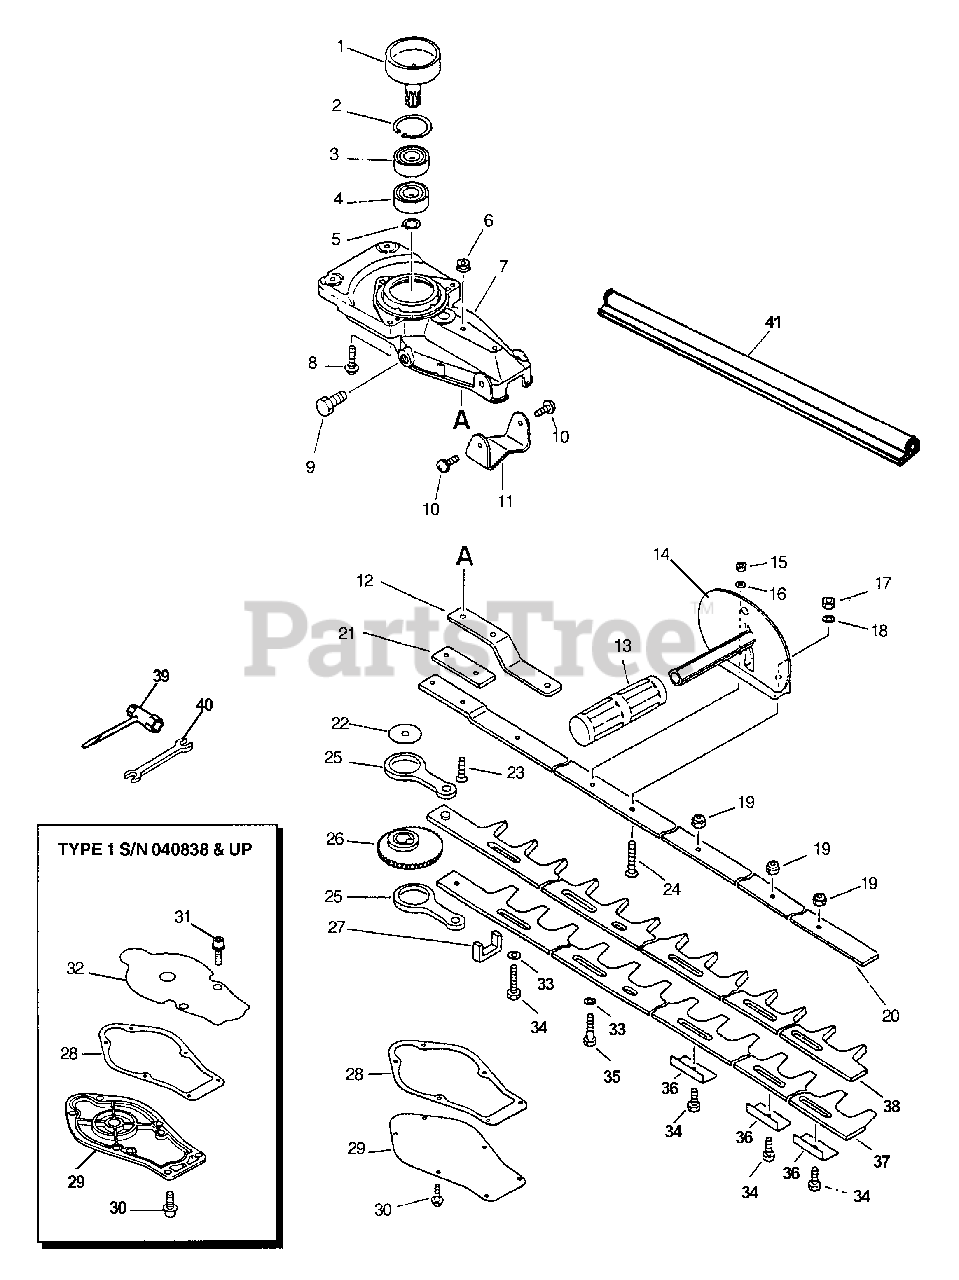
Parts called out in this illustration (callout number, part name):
1	DRUM, CLUTCH
2	RING, RETAINING - 30
3	BEARING, BALL - 6202
4	BEARING, BALL - 6202
5	RING, RETAINING - 14
6	LOCKNUT - 6
7	CASE, GEAR
7	CASE, GEAR - UPPER
8	SCREW - 5X25
9	BOLT - 8X8
10	SCREW - 5X10
11	STAND
12	PLATE, ANGLE
13	GRIP, HANDLE
14	HANDLE - FRONT
15	LOCKNUT - 6
17	LOCKNUT - 5
20	SUPPORT, BLADE
23	SCREW - 6X25
24	SCREW - 5X30
25	ROD, CONNECTING
26	GEAR - DRIVE
27	SEAL, FELT
28	GASKET, GEAR CASE
29	LID, GEAR CASE
29	LID, GEAR CASE - LOWER
30	SCREW - 4X10
30	SCREW - 4X12
31	SCREW - 5X12
32	LID, GEAR CASE
33	WASHER - 6
34	BOLT - 6X22
35	BOLT - 6X35
36	INSULATOR
37	BLADE - LOWER
38	BLADE - UPPER
39	T-WRENCH - 13X19mm
40	SPANNER - 8X10mm
41	COVER, BLADE
